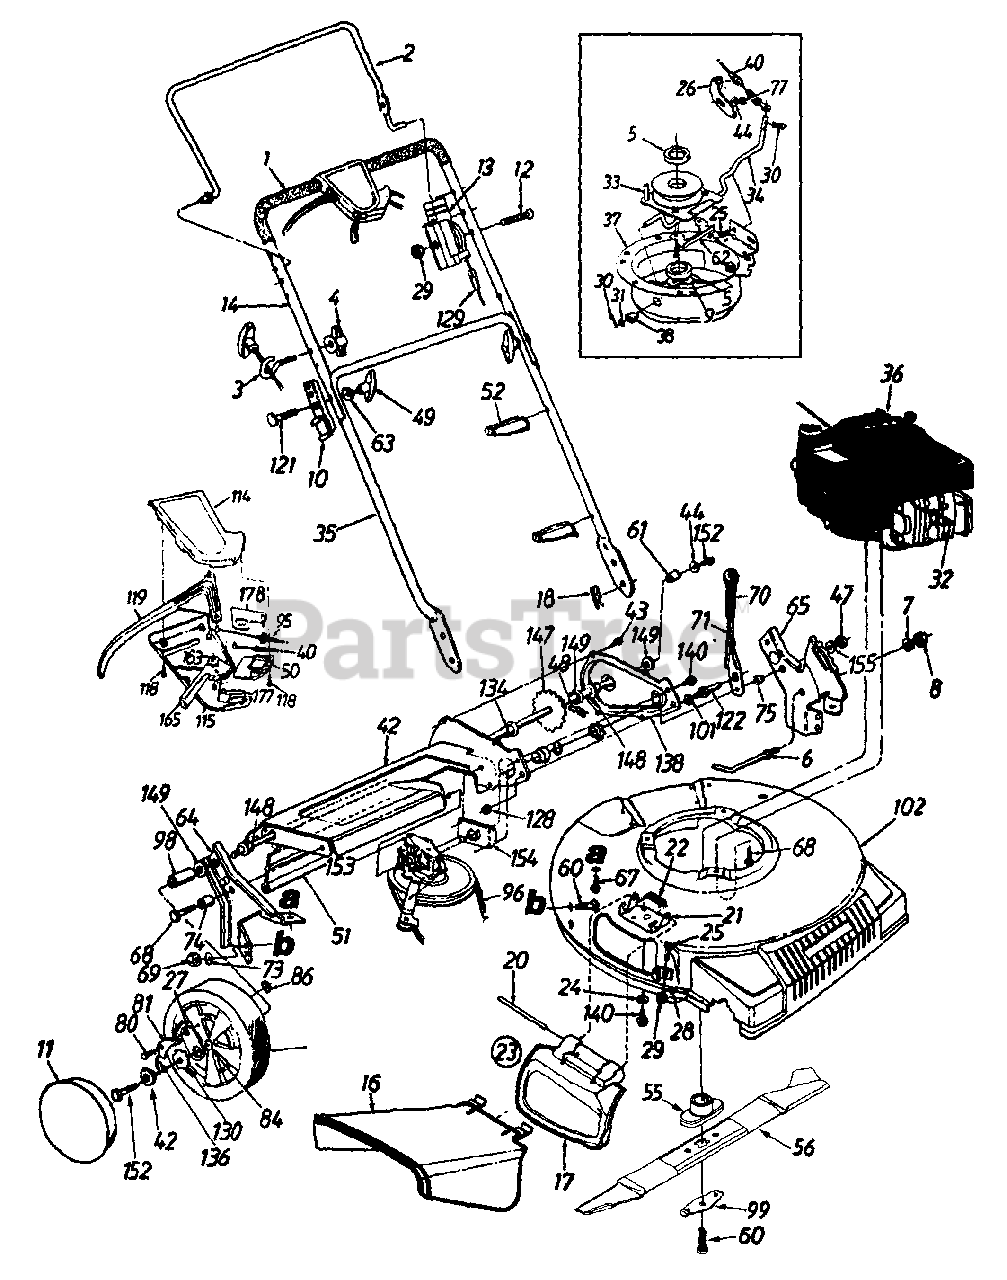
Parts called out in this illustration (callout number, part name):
1	Grip
3	Rope Guide
4	Wing Nut 1/4-20 Thd.
5	Spacer .885" I.D.
6	Belt Guard
7	L-Wash. 1/4" I.D.
8	Hex Nut 1/4-20 Thd.
9	Wave Wash. .88" I.D. x 1.38" O.D.
10	Grass Catcher Bracket
11	Hub Cap
12	Oval C-Sunk Mach. Scr.
13	Throttle Body
16	Side Chute Deflector
17	Mulch Plug
18	Internal Cotter Pin 5/16" Dia.
20	Hinge Pin
22	Torsion Spring
23	Mulch Plug Ass'y. Comp.
24	Bell-Wash. .265" I.D. x .75" O.D.
25	Carriage Bolt 1/4-20 x .5" Lg.
30	Cotter Pin 3/32" Dia. x .75"
31	Fl-Wash. .328" I.D. x .68"
32	Spark Plug Insulator
33	Lower Pulley Half Ass'y.
34	Shift Rod
36	Engine - Craftsman Model
40	6-Spd. Cable
44	Bell-Wash. 1/4" I.D.
47	Hex Patch L-Nut 3/8-24 Thd.
48	#48 Chain .500" Pitch x 38 Links
49	Hand Knob
50	Cable Mounting Cap
51	Rear Flap 4.8" x 17.5" Lg.
52	Cable Tie
55	Blade Adapter
56	21" Mulching Blade
60	Hex Bolt 3/8-24 x 2.5" Lg.
61	Spacer .513" I.D.
67	Hex B-Tap Scr. 5/16-18
68	Hex TT-Tap Scr. 3/8-16
69	Hex Nut 5/16-18 Thd.
71	Height Adj. Lever
73	Bell-Wash. 5/16" I.D.
74	Spacer .383" I.D.
75	Shld. Spacer .5" Dia.
77	Hex L-Nut 1/4-20 Thd.
80	Shld. Scr. .342" Dia. x .268
81	Pawl - R.H.
84	Sleeve Bearing 1/2" I.D.
86	Weld Top L-Nut 1/4-20 Thd.
95	S.P. Cable
96	"V"-Belt
98	Sleeve .526" I.D.
99	Blade Bell Support
115	Lower Control Housing
118	Fl-"C"-Sunk Hd. Tap Scr. #10 x .75" Lg.
119	Control Lever
121	Curved Hd. Bolt 5/16-18 x 2" Lg.
122	Shld. Pin 1.43" Lg.
128	Hex Jam Nut 3/8-24 Thd.
129	Control Cable - 51"
130	Ratchet Wheel 1.62" O.D.
134	Hex Flange Bearing
136	Spring - Nylon
147	Rear Shaft Ass'y. 21.44" Lg.
148	Hex Flange Brg. .506" I.D.
149	Fl-Wash. .531" I.D. x .930"
152	Hex Bolt 1/4-20 x .62" Lg. (Grade 5)
153	Transmission Comp.
155	Fl-Wash. .385" I.D. x .87" O.D.
163	Gear Insert
165	6-Spd. Shift Lever
177	Shift Lever Spring
178	6-Spd. Rack Cable Brkt.
